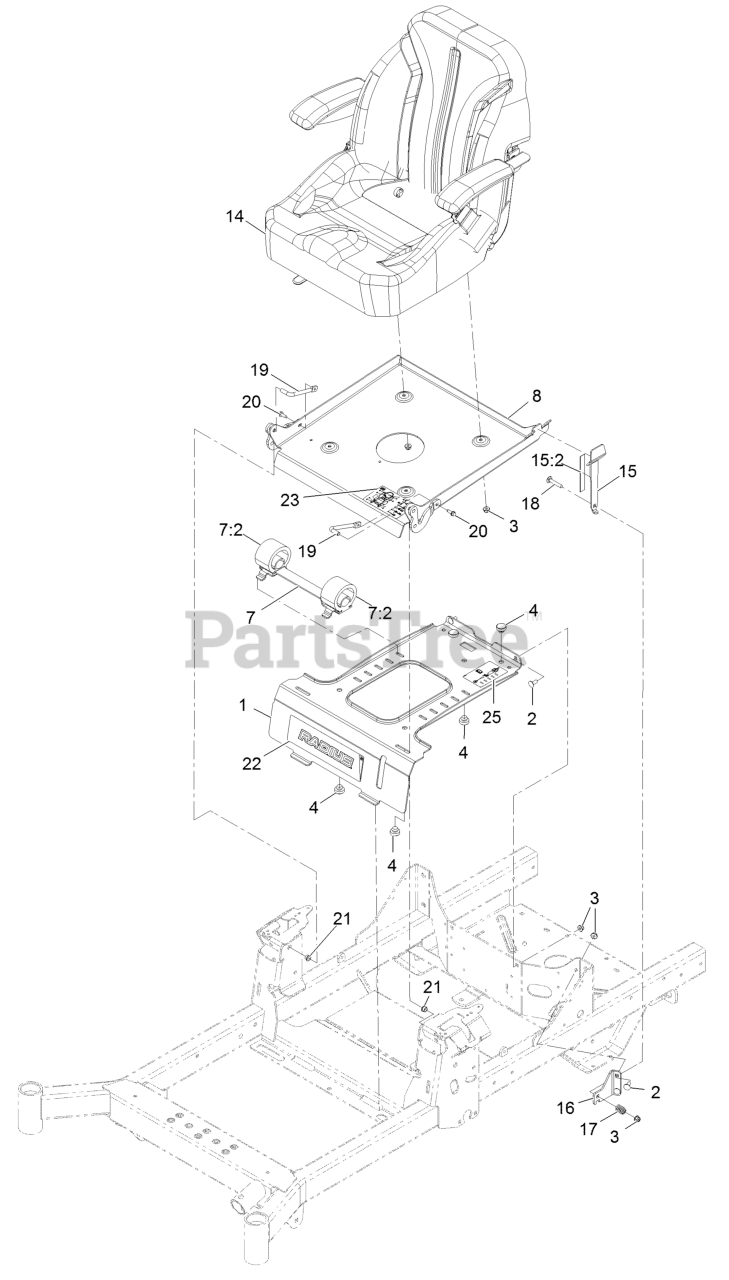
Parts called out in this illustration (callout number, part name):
1	PLATE-RETAINER, TANK
2	SCREW-CARR
3	NUT-HF, NI
4	BUMPER-RUBBER
7	SEAT ISOLATOR ASM
7:2	ISOLATOR-SEAT
8	MOUNT-SEAT
14	ASM-SEAT
15	LATCH SEAT ASM
15:2	STRIP-POLY WEAR
16	BRACKET-LATCH
17	SPRING-COMPRESSION
18	SCREW-CARR
19	PIN-PIVOT, SEAT
20	SCREW-HWH, THREAD ROLL
21	BUSHING-FLANGED
22	DECAL-RADIUS LOGO
23	DECAL-AID, SERVICE
25	DECAL-SEAT SUSPENSION
